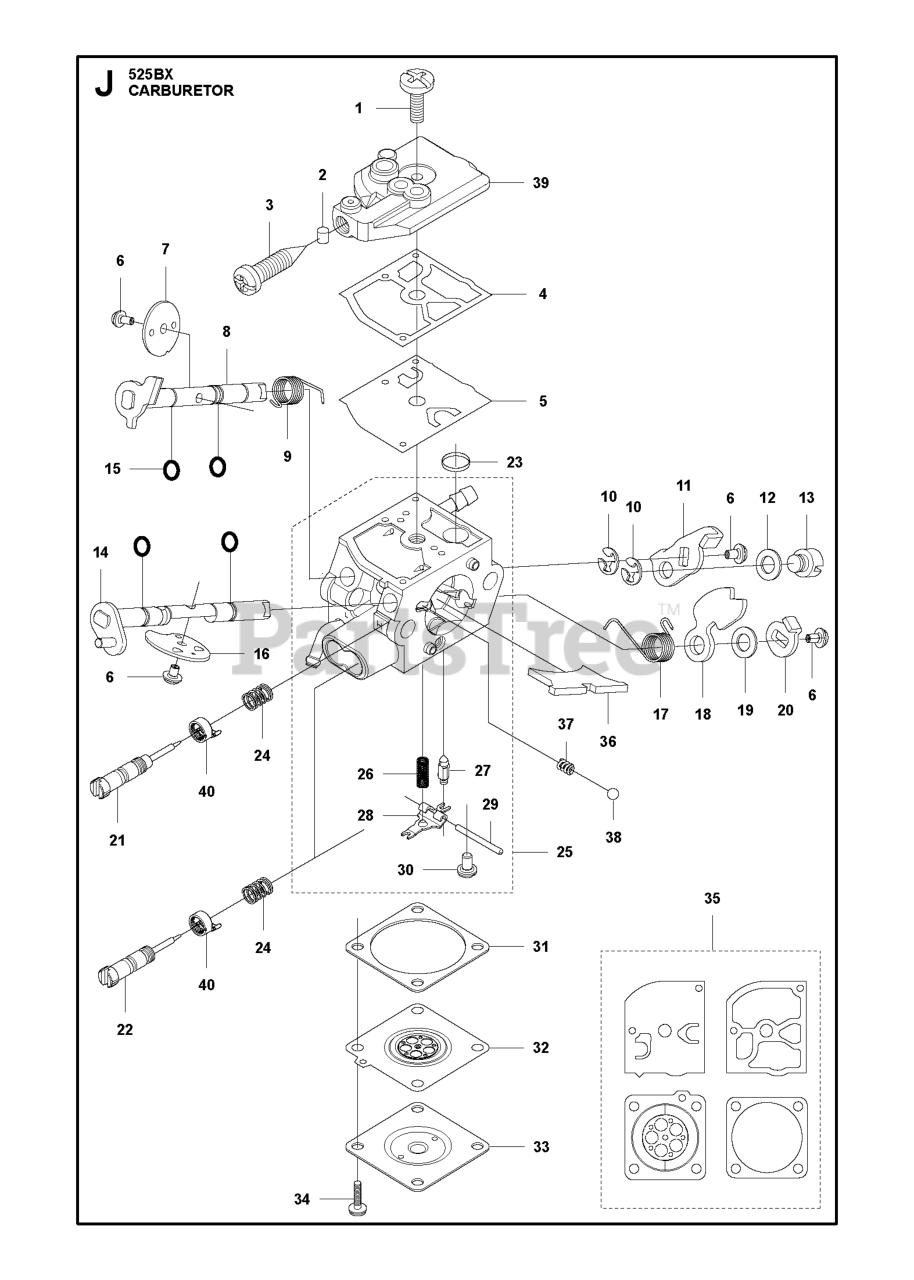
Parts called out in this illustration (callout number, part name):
4	GASKET PUMP
5	DIAPHRAGM PUMP
7	VALVE THROTTLE
8	SHAFT ASSY THROTTLE
9	SPRING THROTTLE RETURN
14	SHAFT ASSY CHOKE
16	VALVE CHOKE
17	SPRING RETURN
21	SCREW IDLE MIXTURE
22	SCREW MAIN MIXTURE
25	BODY ASSY, CARBURETTOR
26	SPRING
27	VALVE INLET
28	LEVER
29	PIN
30	SCREW M3X6
31	GASKET METERING CHAMBER
32	DIAPHRAGM ASSY METERING
33	COVER METERING CHAMBER
34	SCREW M3X7
35	GASKET KIT
36	PLATE SPLIT
37	SPRING FRICTION
38	BALL STEEL
39	PUMP COVER
